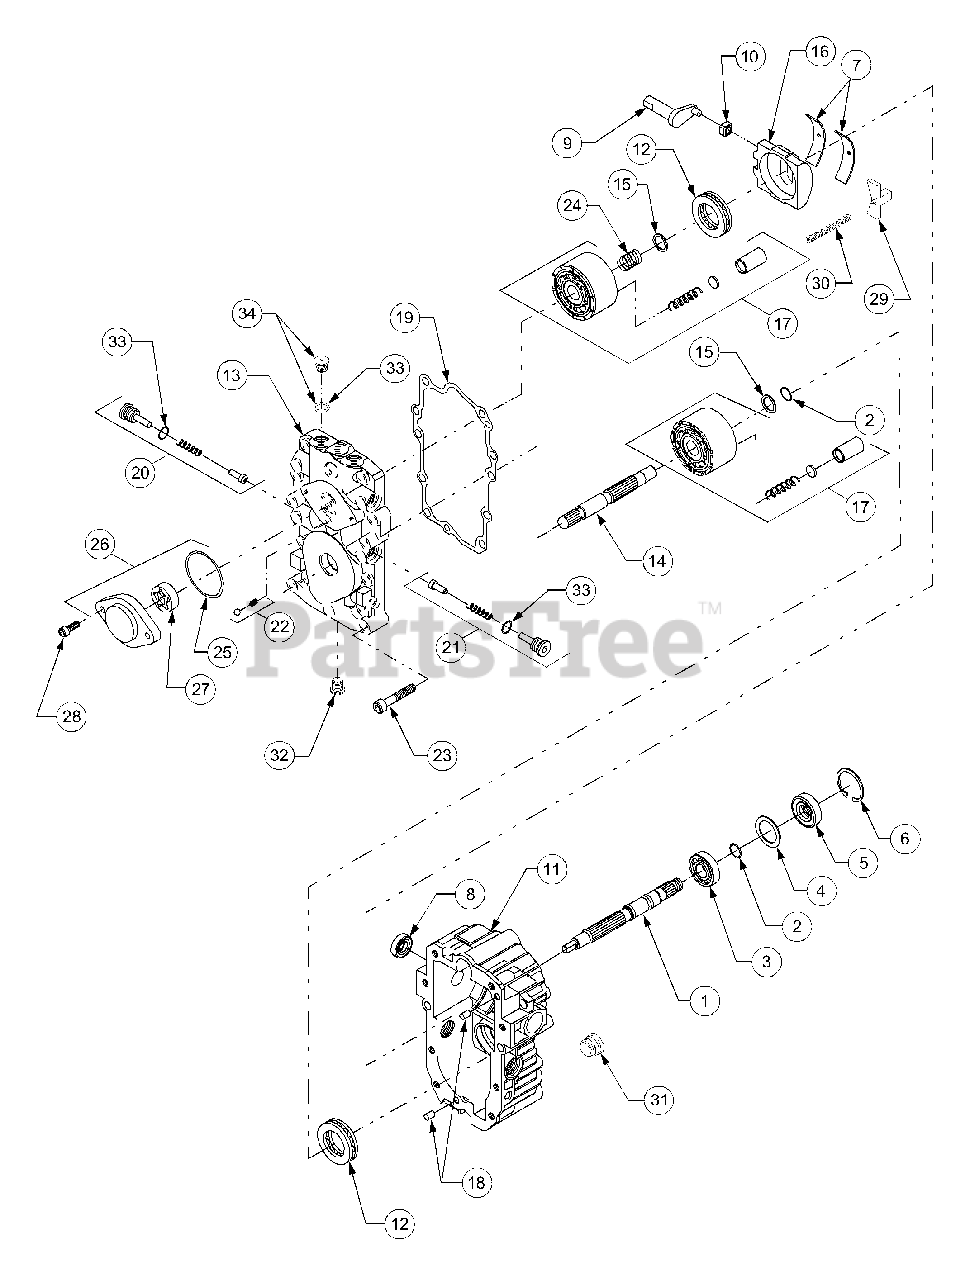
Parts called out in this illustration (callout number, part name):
1	Shaft, Pump (Splined)
2	Ring, Retaining
3	Bearing, Ball
6	Ring, Retaining
7	Bearing, Cradle
9	Arm, Trunnion
10	Guide, Slot
11	Housing Kit
12	Bearing Assembly, Thrust Ball
13	Center Section Kit
14	Shaft, Motor
15	Washer, Block Thrust
16	Swash Plate
17	Block Assembly
19	Gasket, Center Section
20	Kit, Check Valve
21	Kit, Orificed Check Valve
22	Kit, Charge Relief Valve
23	Screw, Socket Hd
24	Spring, Block
26	Kit, Charge Pump
27	Gerotor Assy
28	Screw, Socket Hd
30	Spring, Compression
